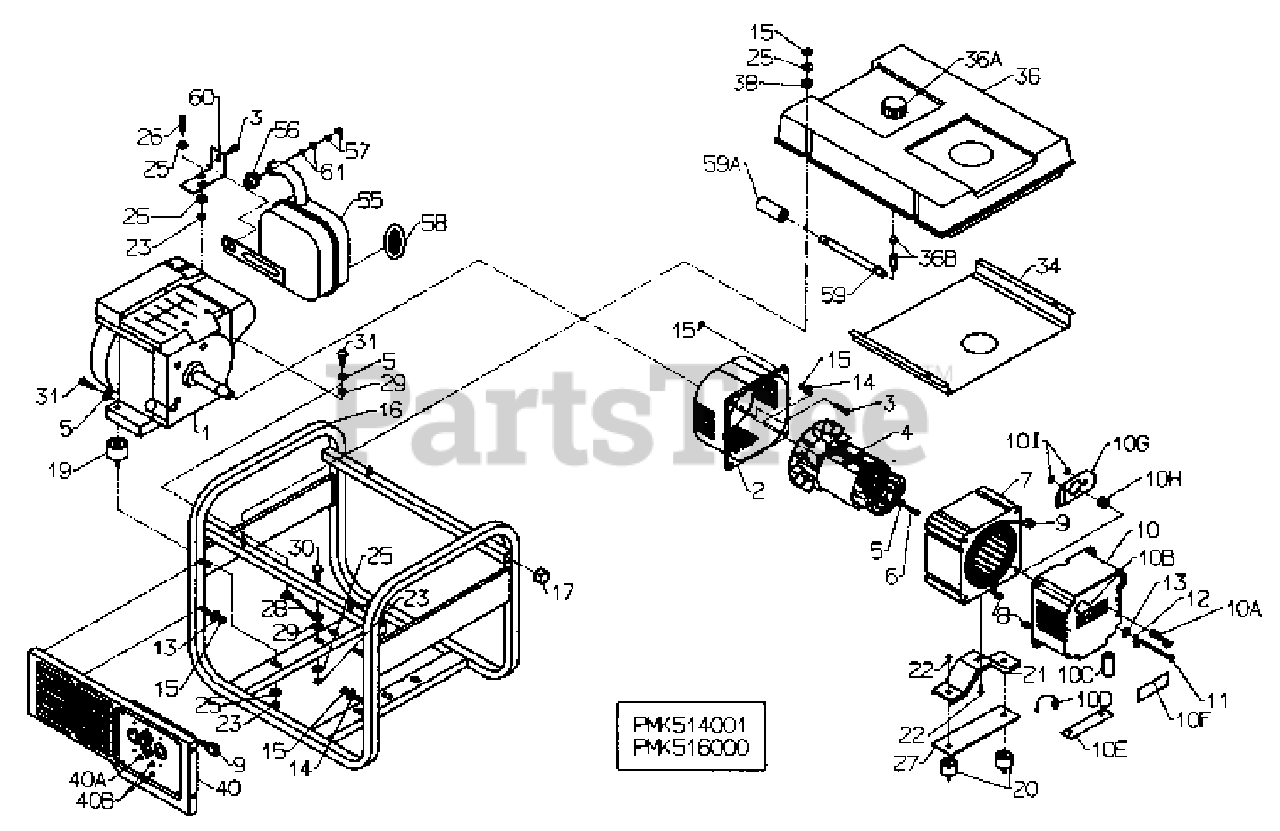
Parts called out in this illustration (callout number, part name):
2	ADAPTER,ENGINE
3	BOLT,3/8-16X3/4
5	WASHER,LOCK 5/16
6	BOLT,HEX 5/16-24X6-5/8
8	CONNECTOR,ENDBELL
9	CONNECTOR,PANNEL
10	ENDBELL,WIRED
10B	BEARING,NEEDLE
10E	HEAT SINK,DIODE
10F	COVER,BRUSH
10G	SHIELD,ENDBELL
10H	TOLERANCE RING
10I	RETAINING CLIP
11	BOLT,HEX1/4-20X6
12	LUG,GROUND
13	WASHER,FLAT
14	WASHER,STAR
15	NUT,NYLOC
17	CAP,PLASTIC
19	MOUNT,ENGINE
20	MOUNT,ENGINE
21	BRACKET,STATOR
22	BOLT,5/16-18/1/2
23	NUT,NYLOC 5/16
25	WASHER,FLAT 5/16
26	BOLT,5/16-18X11/2
27	BRACKET,STATOR
28	WIRE,GROUND
29	WASHER,STAR 5/16
30	BOLT,5/16-18X3/4
31	BOLT,5/16-18X11/4
34	SHEILD,HEAT
36	TANK ASSY,FUEL
36A	CAP,FUEL
36B	FUEL VALVE/BUSHING
38	BUSHING,STEP
40	CONTROL PANAL,COMPLETE
40A	CIRCUT BREAKER,20AMP
40B	CIRCUT BREAKER,35AMP
56	GASKET,MUFFLER
58	SCREEN,SPARK ARRESTOR
59	CLAMP,FUEL LINE
59A	FOAM,INSULATION
60	BRACKET,MUFFLER
61	WASHER,LOCK 8MM
